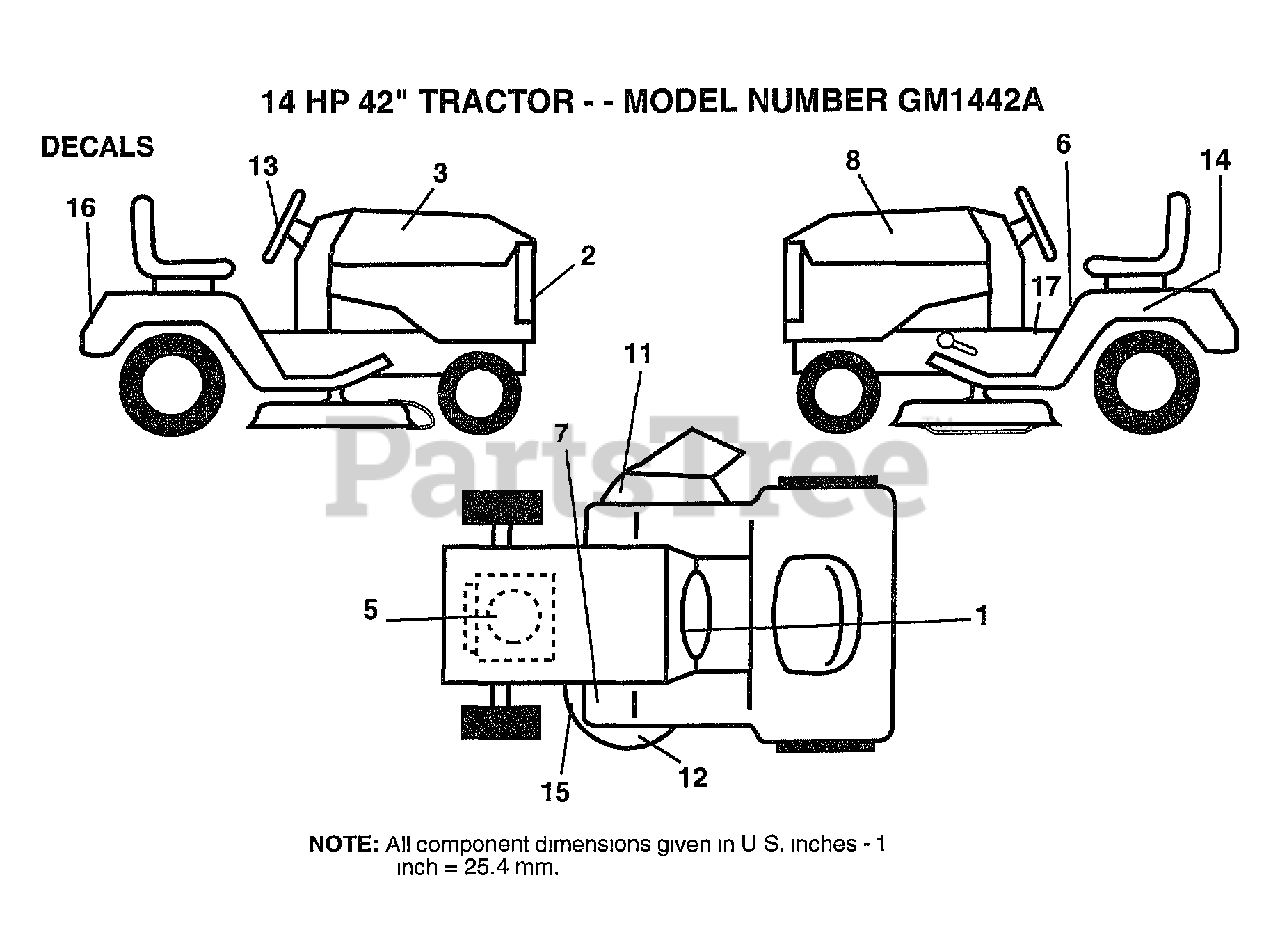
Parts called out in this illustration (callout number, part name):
1	DECAL.DASH.INSTR.
3	DECAL.HOOD.RH
5	DECAL.ENG.272750
6	DECAL CAUTION
7	DECAL T
8	DECAL.HOOD.LH
11	"DECAL, WARNING"
13	DECAL.INSRT.STRG
14	DECAL
15	DECAL.V.BELT
16	DECAL.FENDER
17	DECAL BRAK PARK
